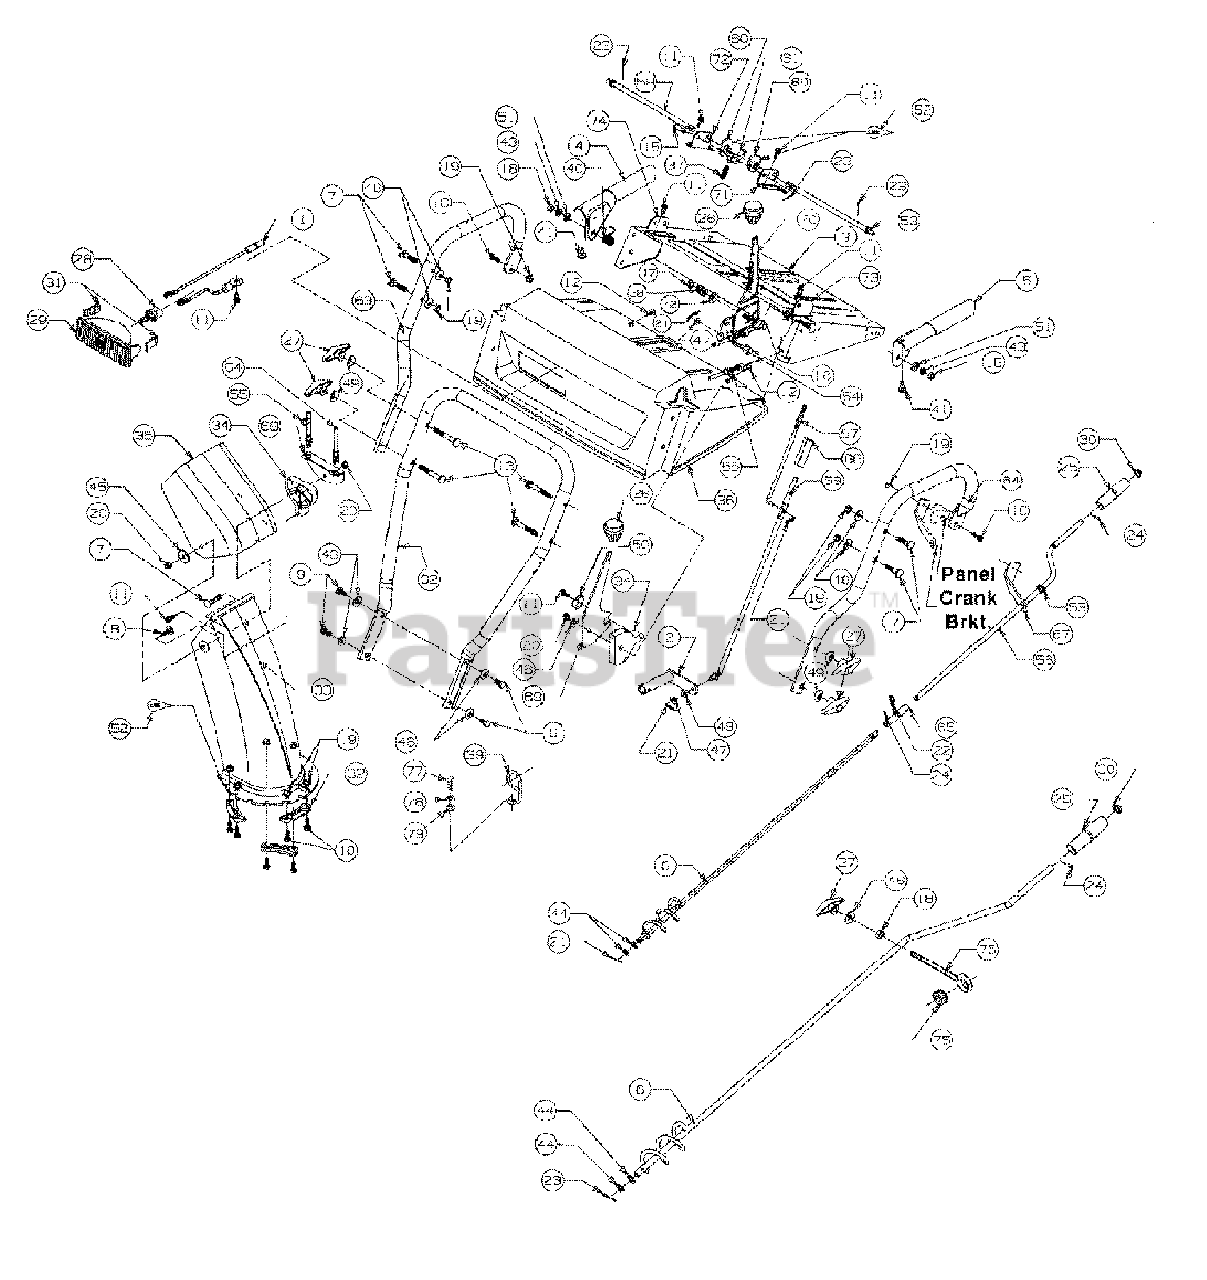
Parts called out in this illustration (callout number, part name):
1	Harness-Light
2	Arm-Shift
4	Handle-Engagement-R.H.
5	Handle-Engagement-L.H.
6	Crank-Chute (623,633)
6	Crank-Chute (653,663)
7	Bolt-Carriage
8	Bolt-Carriage
9	Screw-Hex
10	Screw-Hex
11	Screw-Washer Head-Hex
12	Screw-Hex
13	Bolt-Carriage
15	Pin-Clevis
16	Ferrule
17	Nut-Hex Lock
18	Nut-Hex
19	Nut-Hex Lock
20	Nut-Hex Lock
21	Pin-Cotter Internal
22	Pin-Cotter
23	Pin-Cotter
24	Pin-Roll
25	Knob-Chute Crank
26	Knob-Shift
27	Knob-Wing Nut
29	Housing-Lamp
30	Cap-Push
31	Clip-Retaining
32	Keeper-Chute
33	Chute-Lower
34	Guide-Cable
35	Chute-Upper
36	Panel-Handle
37	Spring
38	Spring
39	Wire-Control
40	Spring
41	Bumper
42	Washer-Bell
43	Washer-Lock
44	Washer-Flat
45	Washer
46	Washer-Bell
47	Washer-Flat
48	Washer-Lock
49	Washer-Saddle
50	Washer
51	Washer
52	Lubricant
53	Bushing-Plastic
54	Cable-Chute Control
55	Cable-Chute Control
56	Crank-Chute
57	Rod-Shift Upper
58	Rod-Shift Lower
59	Rod-Cam
60	Cam-Handle Lock
61	Pawl-Handle Lock
63	Handle-R.H.
64	Handle-L.H.
65	Spacer
66	Connector
67	Bracket
69	Handle-Chute Tilt
70	Handle-Shift
71	Bracket-Handle Support-L.H.
72	Bracket-Handle Support-R.H.
74	Bracket-Handle Support-R.H.
75	Grommet Rubber (623,633)
76	Eyebolt-Chute (623,633)
77	Screw-Washer Head-Hex (623,633)
78	Washer-Lock (623,633)
79	Washer-Flat (623,633)
